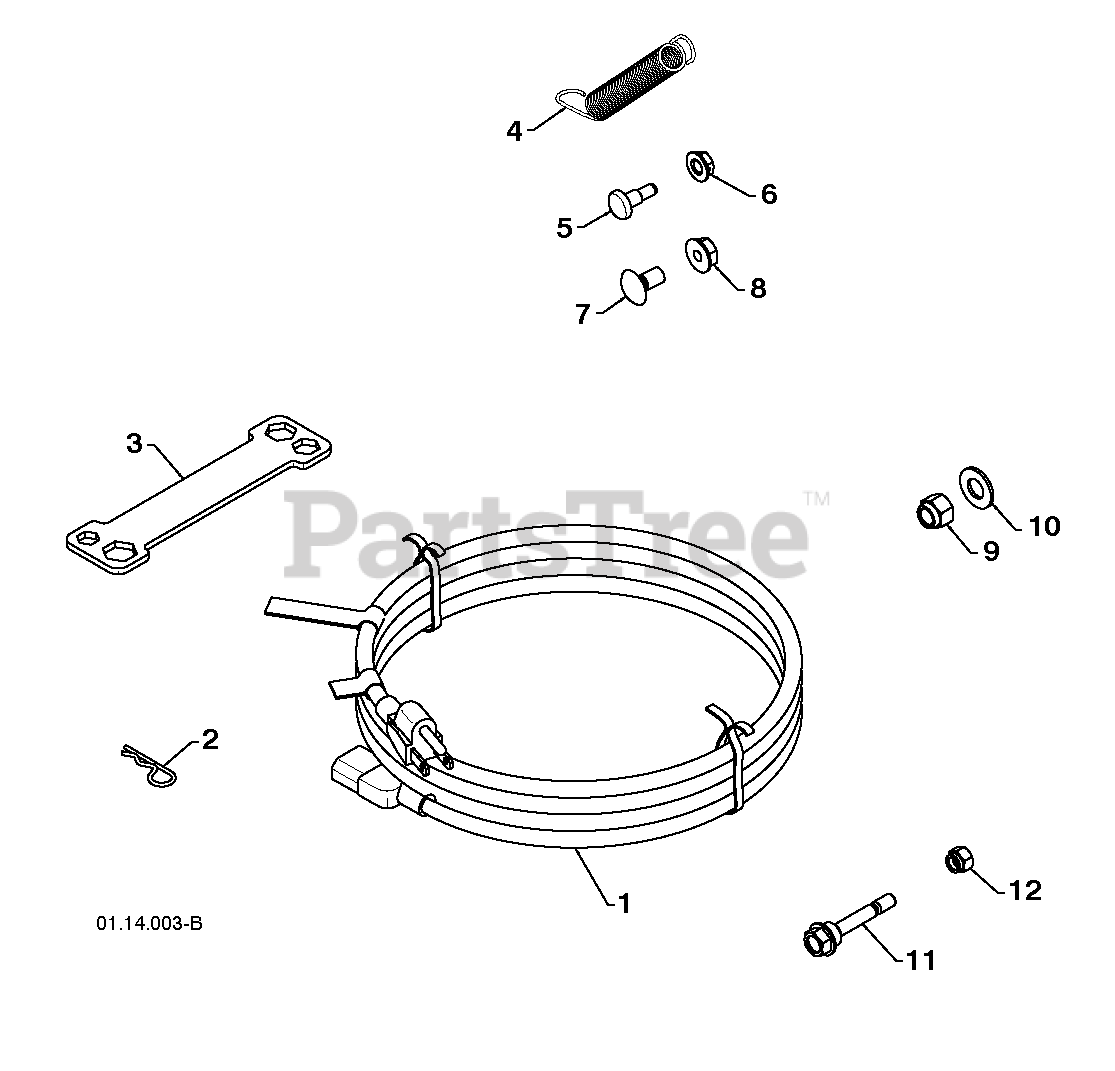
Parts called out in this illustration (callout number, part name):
1	POWER CORD
2	RETAINER PIN
3	WRENCH
4	REMOTE SPRING
5	SHOULDER BOLT 1/4-20
6	LOCKNUT 1/4-20
7	CARRIAGE BOLT 5/16-18 X 5/8
8	LOCKNUT 5/16-18
9	LOCKNUT 3/8-16
10	WASHER 3/8
11	SHEAR BOLT 1/4-20 X 1-13/16
12	LOCKNUT 1/4-20
